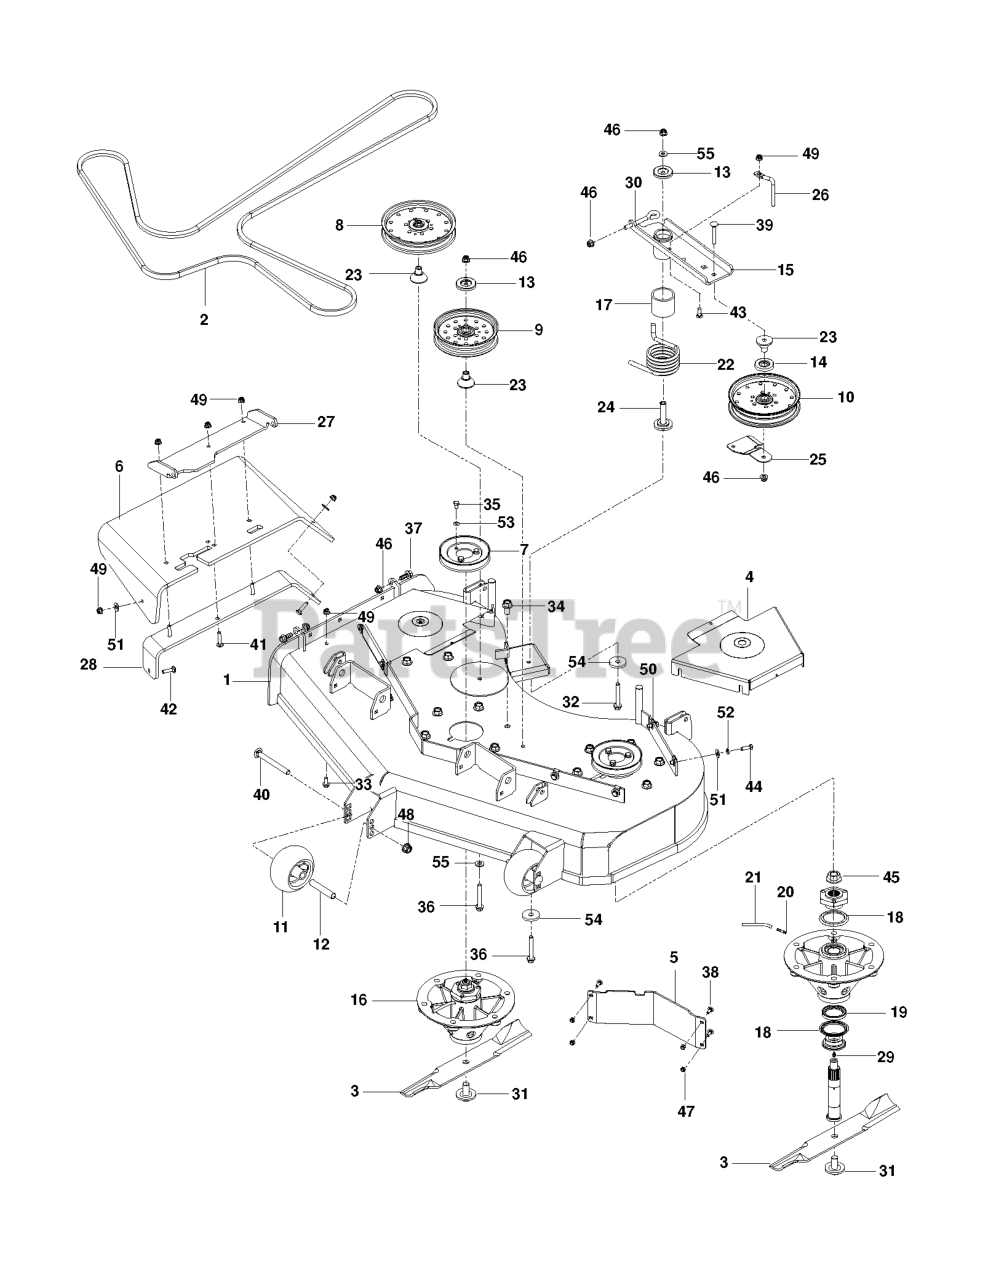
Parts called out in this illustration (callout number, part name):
1	DECK.SVC.48" W/DECALS ORG
3	BLADE 17" HIGHT LIFT
4	SHIELD,BELT, 60" ORANGE
5	BAFFLE, DIVERTER 54"/60" LH
6	CHUTE, DISCHARGE 48-52
7	PULLEY - 5.25
8	PULLEY - 7" NARROW
9	PULLEY IDLER, 6" NARROW
10	PULLEY - IDLER 7"
11	ROLLER, GAUGE .635 BORN
12	TUBE, ROLLER AXLE
13	DUST SHIELD
14	SHIELD, DUST
15	IDLER.ARM.BLACK
16	SPINDLE ASM. 10" ALUMINUM
17	SPACER, IDLER PIVOT
18	SEAL V-RING 55MM
19	SEAL SHAFT
20	ADAPTER, FITTING, TUB
21	WHEEL.9X2.PR.SP.GY
22	SPRING, TORSION, IDLER
23	BEARING, IDLER ARM
24	BEARING, IDLER PIVOT
25	BELT.GUIDE.BLACK
26	BELT KEEPER
27	BRKT - CHUTE MTG BLACK
28	BRKT, CHUTE SUPPORT BLACK
29	ZERK
30	EYE BOLT, 3/8 X 4"
31	BLADE BOLT/WASHER
32	HCS 3/8-16 X 4-1/2 GR 8 ZD
33	HHFS 5/16-18 X 3/4
34	HHFS 1/2-13 X 1 GR5 ZD
35	HCS 5/16-18 X 1/2 GR 5 ZD
36	HHFS 3/8-16 X 2 3/4
37	HHFS 3/8-16 X 1 GRD 5 ZD
38	1/4-20X3/4 CARR BLT
39	CARRIAGE BOLT 3/8-16 X
40	RHSNB 1/2-13 X 4.75 GR5 ZD
41	RHSNB 5/16-18 X 1-1/2 GR 5 ZD
42	BOLT, CARRIAGE 5/16X1-1/4
43	RHSSNB 5/16C X 1.0
44	HCS 5/16C X 1
45	NUT FLANGE 3/4-16
46	NUT 3/8-16 HEX FLG NYLOC ZD
47	NUT.1/4-20.HEX.NYLOC.ZD
48	NUT, 1/2-13 HEX FLG NYLOC ZD
49	5/16-18 NYLOC FLANGE NUT
50	U-CLIP 5/16-18 NUT RETAINER
51	WASHER 5/16 FLAT
52	WASHER.LOCK.HVY.HLCL.SPR.5/16
53	WASH 5/16 DISC SPRING ZD
54	SPINDLE WASHER
55	WASHER, 3/8 THICK
